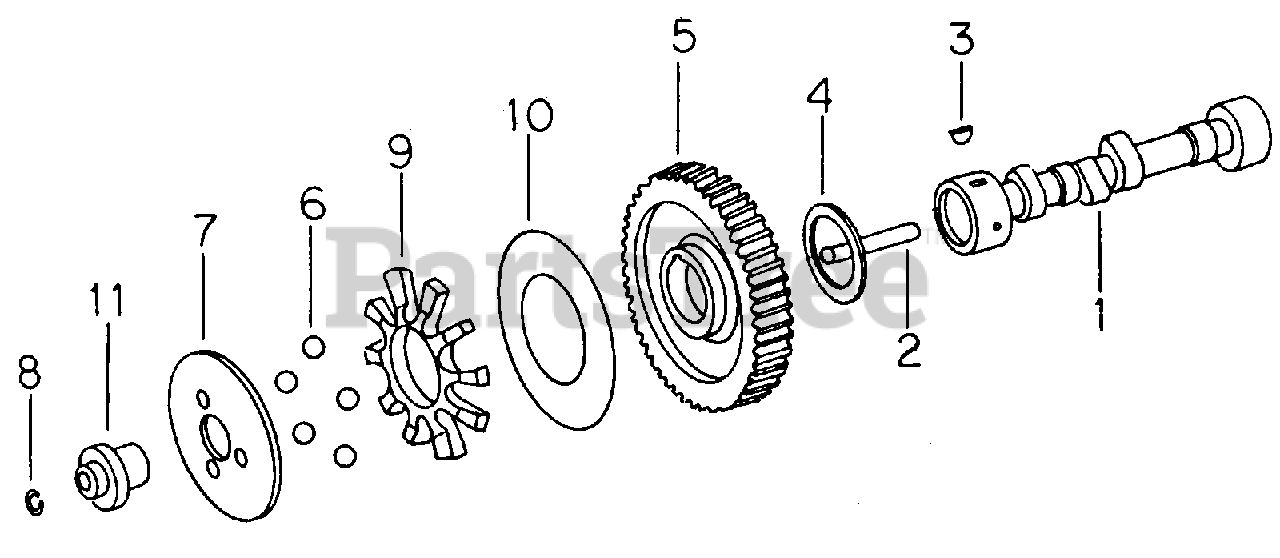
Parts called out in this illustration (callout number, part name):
1	Camshaft
2	Pin, Camshaft
4	Washer, Thrust
6	Ball, Governor Fly
7	Cup, Governor
8	Ring, Retaining
9	Spacer, Flyball
10	Plate, Flyball
11	Hub, Governor Cup
